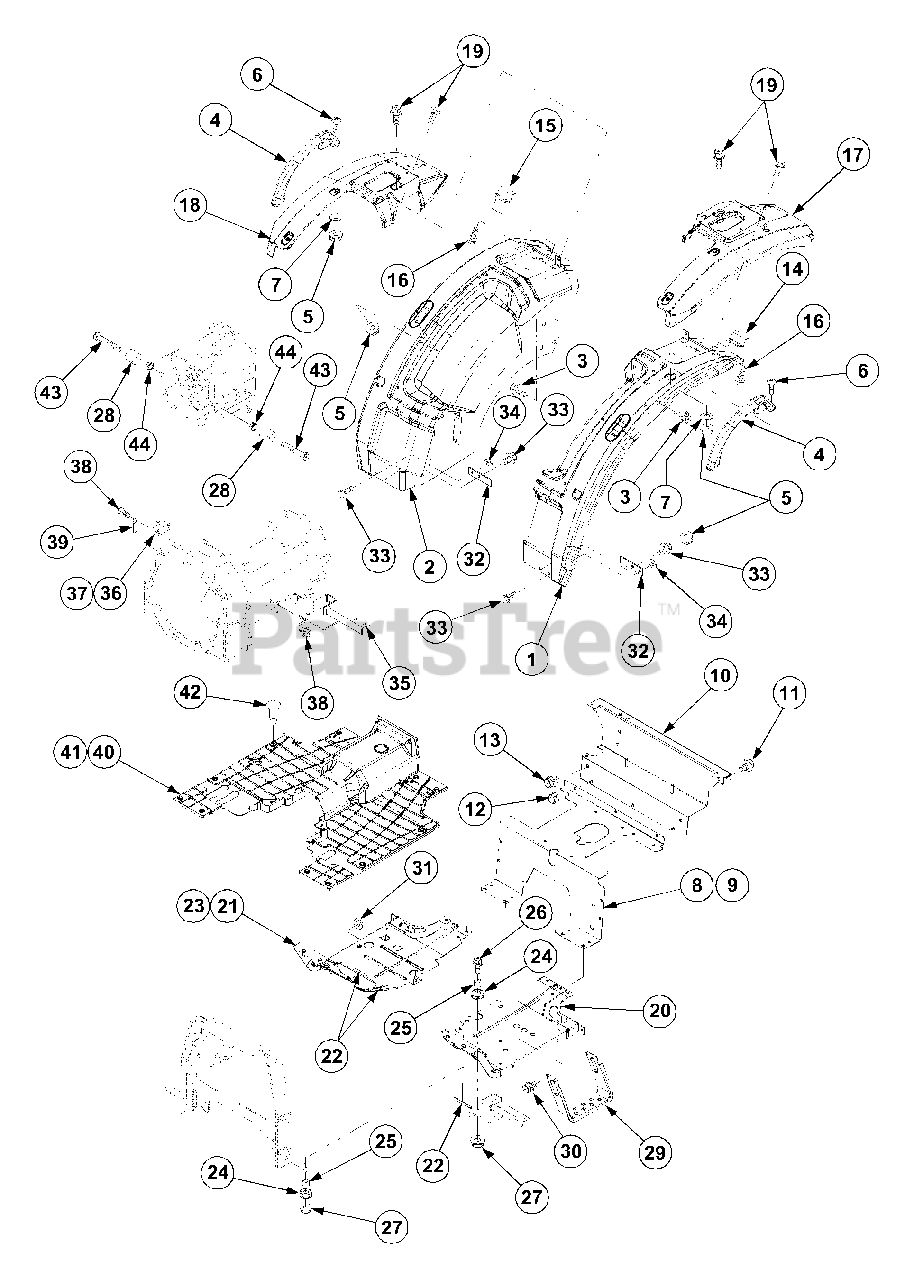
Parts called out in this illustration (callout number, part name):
3	Bolt,w/Washer
8	Cover,Front
11	Bolt,w/Washer
13	Bolt,w/Washer
16	Bolt,w/Washer
17	Cover LH,Fender
18	Cover Rh,Fender
19	Bolt,w/Washer
21	Step RH
23	Step RH
30	Bolt,w/Washer
33	Bolt,w/Washer
35	Bracket LH,Step
36	Bracket RH,Step
37	Bracket RH,Step
38	Bolt,w/Washer
40	Mat,Step
